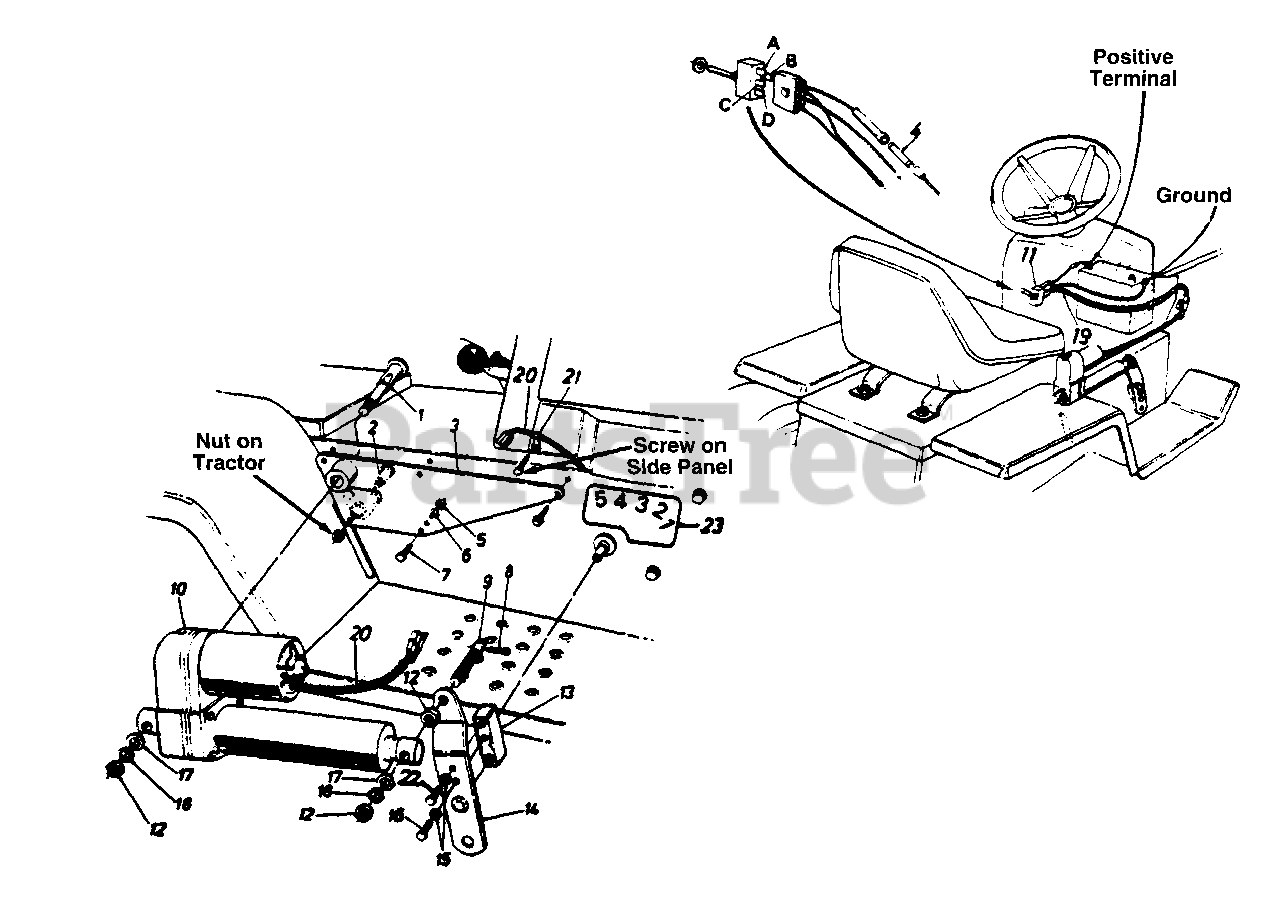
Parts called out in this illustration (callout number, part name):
1	Pivot Pin
2	Shld. Bolt .626" Dia. x .96"
5	Hex Nut 1/4-28 Thd.
6	L-Wash. 1/4" I.D.
7	Hex Bolt 1/4-28 x .75" Lg. (Grade 5)
8	Cotter pin
9	Indicator & Mtg. Pin
10	Electric Actuator
11	Toggle Switch
12	Hex Jam Nut 1/2-13 Thd.
13	Lift Shaft Drive
14	Lift Bracket Ass'y.
15	L-Wash. 5/16" I.D.
16	Hex Bolt 5/16-24 x 1.0" Lg. (Grade 5)
17	Fl-Wash. .53" I.D. x .93" O.D.
18	L-Wash. 1/2" I.D.
19	Wire Harness
20	Plastic Tubing - 7"
21	Clamp
22	Hex Bolt 5/16-18 x 1" Lg. (Grade 5)
23	Label
A	Blue Wire
B	Yellow Wire
C	Black Wire
D	Red Wire
